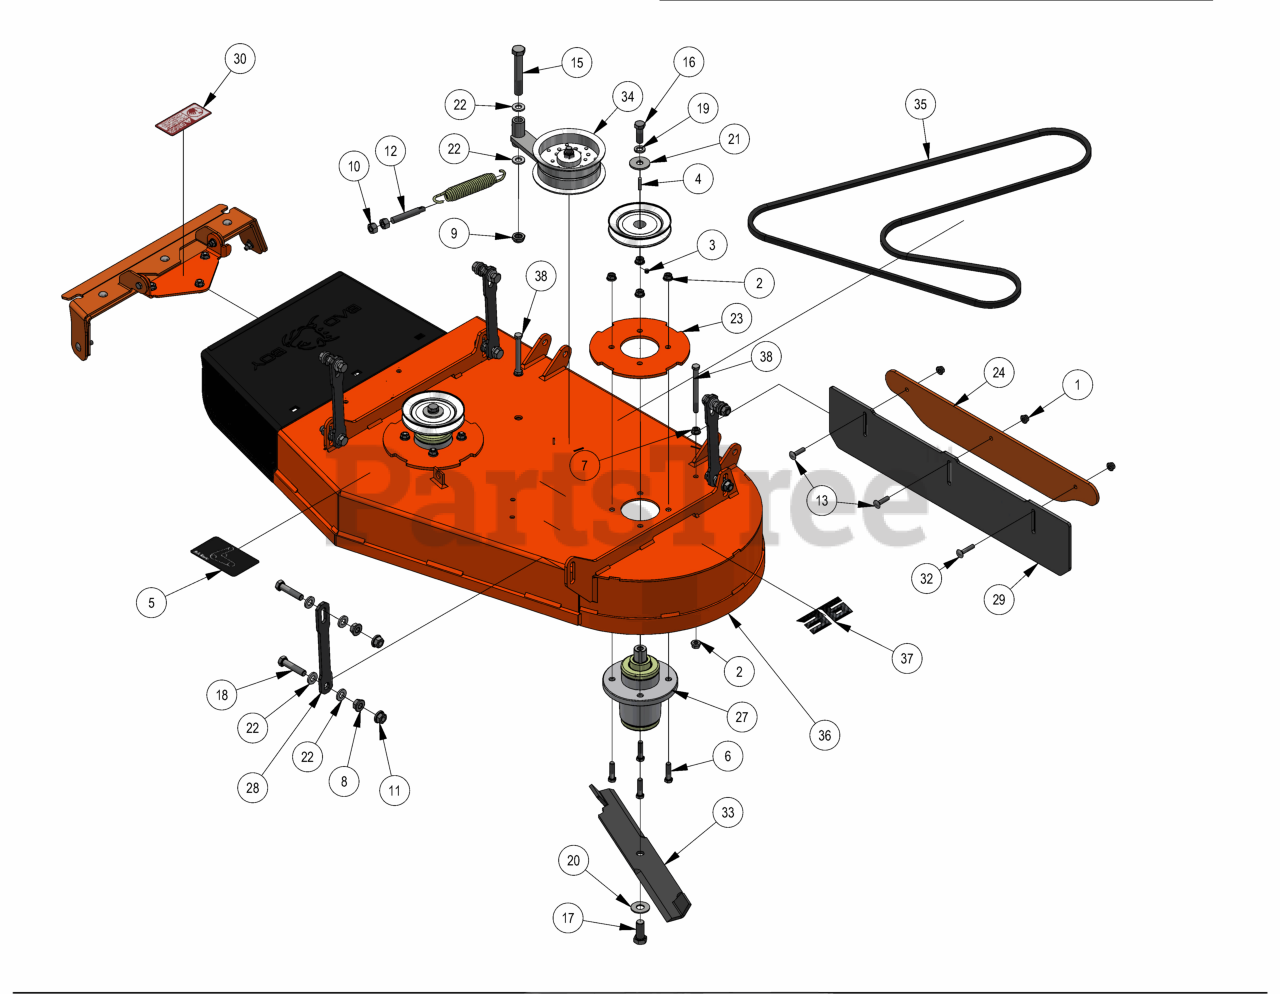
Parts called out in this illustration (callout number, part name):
1	5/16-18 NYLON INSERT FLANGE LOCKNUT ZINC
2	3/8-16 NYLON INSERT FLANGE LOCKNUT (GR.F) ZINC
3	5/16-24 X 1/4 SOCKET SET SCREW (CUP PT) PLAIN
4	1/4 X 1 SQ MACHINERY KEY 1018 STL PLN
5	2017 Walk Behind 36" Deck Belt Route
6	3/8-16 X 1-1/2 HEX CAP SCREW (GR.5) ZINC
7	3/8-16 HEX SERRATED FLANGE NUT HARD/ZINC
8	1/2-13 HEX SERRATED FLANGE NUT HARD/ZINC
9	5/8-11 NYLON INSERT JAM LOCKNUT ZINC
10	1/2-13 HEX NUT ZINC
11	1/2-13 NYLON INSERT FLANGE LOCKNUT ZINC
12	All Thread
13	5/16-18 X 1-1/4 CARRIAGE BOLT ZINC
14	3/8-16 X 3/4 HEX CAP SCREW (GR.5) ZINC
15	5/8-11 X 4 HEX CAP SCREW (GR.8) ZINC YELLOW
16	1/2"-20 x 1 1/2 - Grade 5 Fine Thread Bolt
17	5/8-18 X 1-1/2 HEX CAP SCREW (GR.8) ZINC YELLOW
18	1/2-13 X 2-1/4 HEX CAP SCREW (GR.5) ZINC
19	1/2 SPLIT LOCKWASHER (GR.8) ZINC/YELLOW
20	5/8 USS FLAT WASHER (1-3/4" OD) GR.8 ZINC YELLOW
21	1/2 BELLEVILLE WASHER (1-5/8 OD X .140 THK) ZINC
22	.505 ID X 1.000 OD X .125 THICK FLAT WASHER NYLON
23	Deck Spindle Support Plate
24	Striping Kit Plate
25	5" Spindle Deck Pulley
26	Deck Idler Spring
27	OUTLAW SPINDLE ASSEMBLY
28	23WB Deck Hanger
29	2023 MZ Stripping Kit Rubber
30	Danger Decal-Spindle/Discharge
31	ZT Chute Assembly
32	5/16-18 X 1-1/2 CARRIAGE BOLT ZINC
33	54" Fusion Blade for Avenger/ZT/Mav/Outlaw/Revolt
34	Deck Idler Assembly 36" Walk Behind
35	2020 Walk-Behind 36 Deck Belt
36	Walkv3 36 Deck-2023
37	36" Deck Decal
38	3/8-16 X 4-1/4 HEX CAP SCREW (GR.5) ZINC
